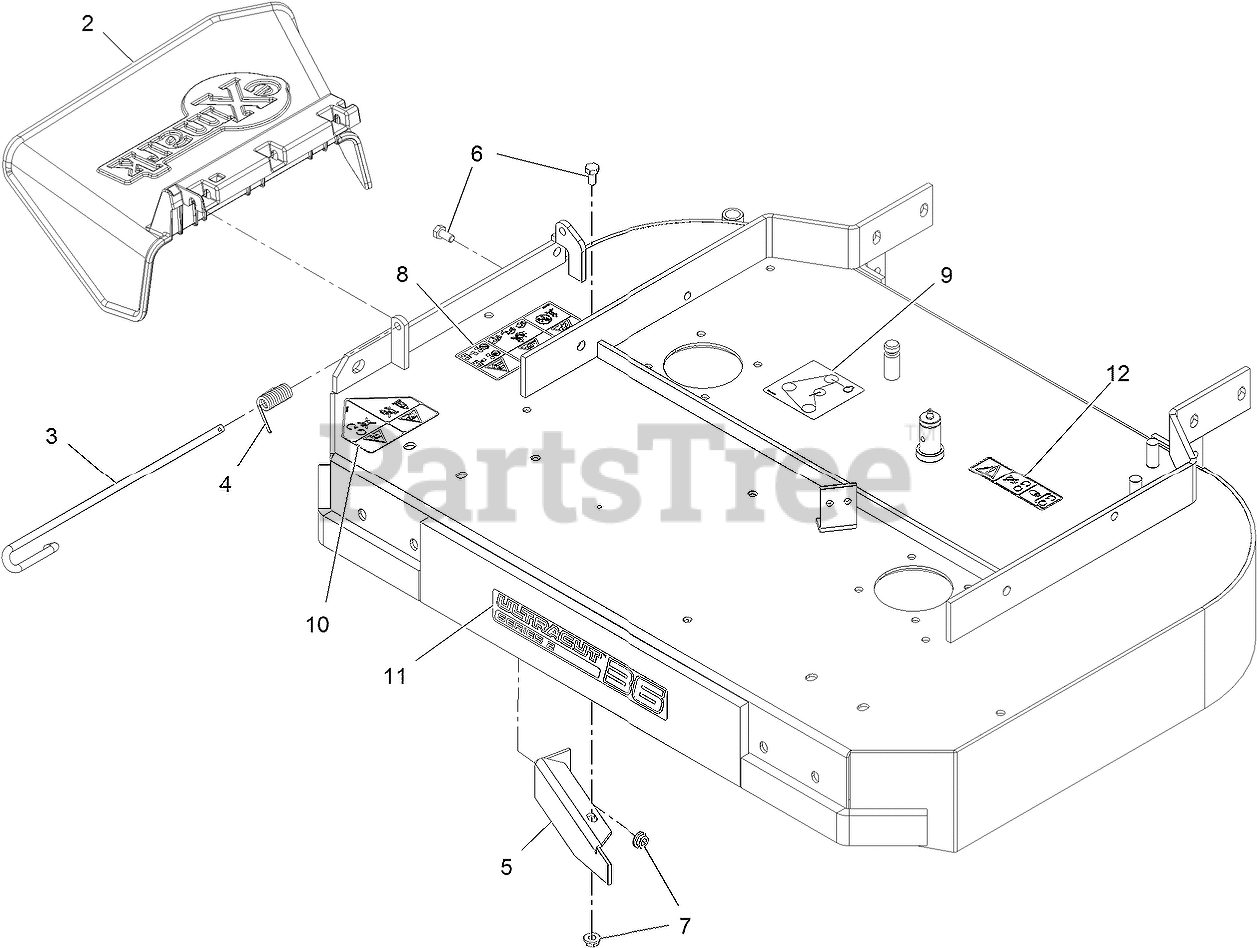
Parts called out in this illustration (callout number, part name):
2	CHUTE DEFLECTOR XRK M056
3	PIN-CHUTE
4	SPRING, TORSION
5	BAFFLE-DOGLEG
6	SCREW-HH
8	DECAL-WARNING THROWN OBJ
9	DECAL-BELT ROUTING 32-36
10	DECAL-DANGER
11	Decal-Ultracut 36 Series 2
12	DECAL-COVER, MISSING
